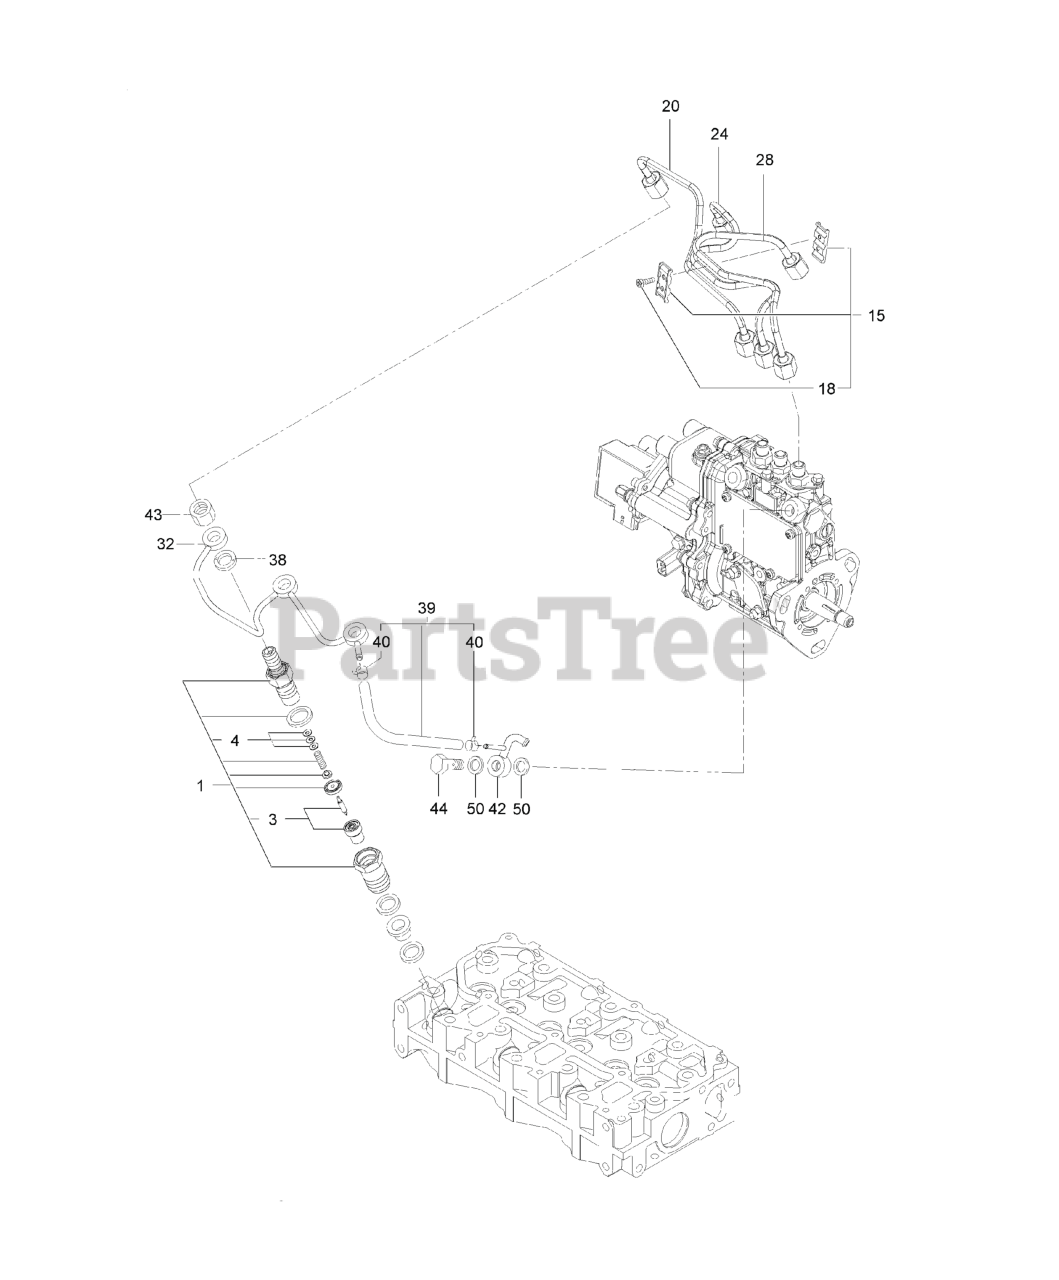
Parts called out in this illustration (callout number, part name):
1	NOZZLE ASM
3	NOZZLE ASM
4	SHIM SET-ADJUSTING
15	RETAINER-PIPE
20	PIPE ASM
24	PIPE ASM
28	PIPE ASM
32	PIPE ASM
39	HOSE ASM
40	CLAMP-HOSE
42	JOINT-OVER FLOW
43	NUT-NOZZLE
44	VALVE ASM-CHECK
50	WASHER-SEAL
